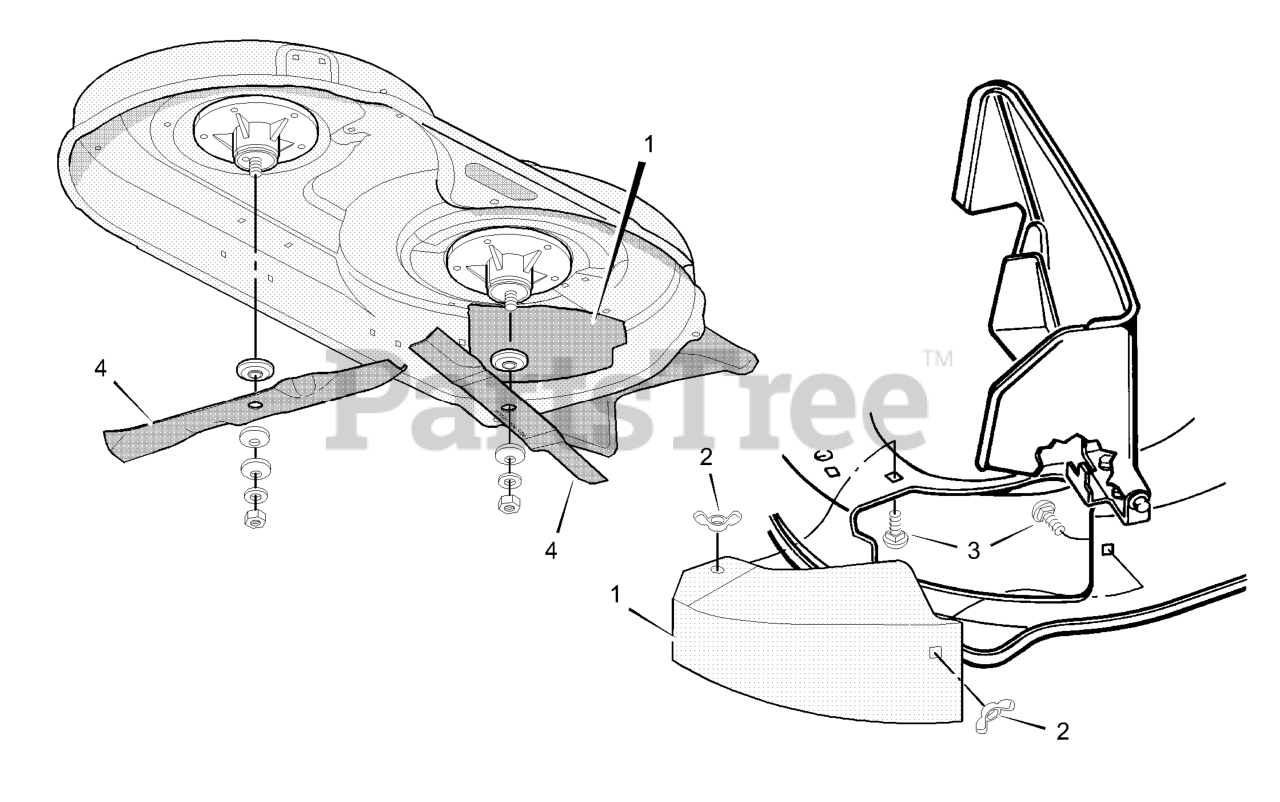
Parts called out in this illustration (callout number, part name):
1	Mulcher Plate
2	Wingnut
3	Carriage Bolt
4	Blade, 3n1
